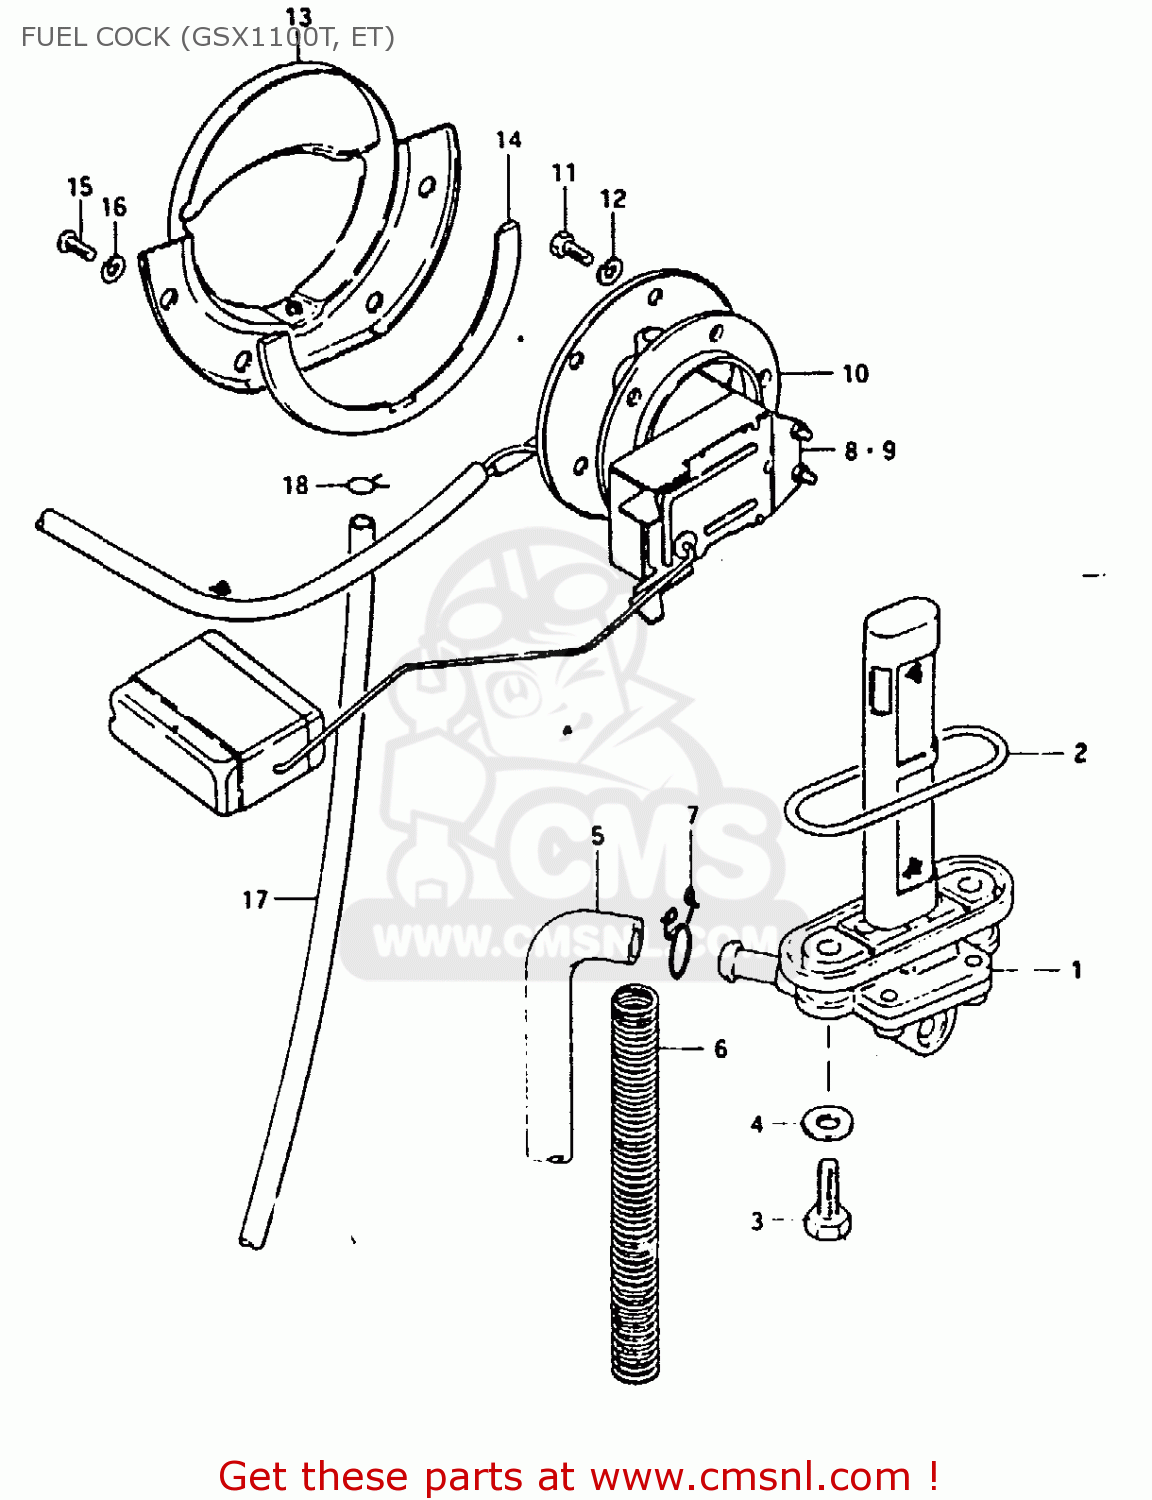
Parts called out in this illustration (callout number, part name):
1	COCK ASSY,FUEL
2	GASKET (NAS)
3	SCREW (6X25)
4	GASKET
5	HOSE
6	SPRING
7	CLIP
9	GAUGE, FUEL LEVEL (24L)
10	GASKET,FUEL LEVEL GAUGE (NAS)
11	BOLT
12	LOCK WASHER
13	PLATE,FUEL DRAIN
14	GASKET,FUEL DRAIN PLATE (NAS)
15	SCREW
16	LOCK WASHER
17	HOSE,FUEL
18	CLIP
